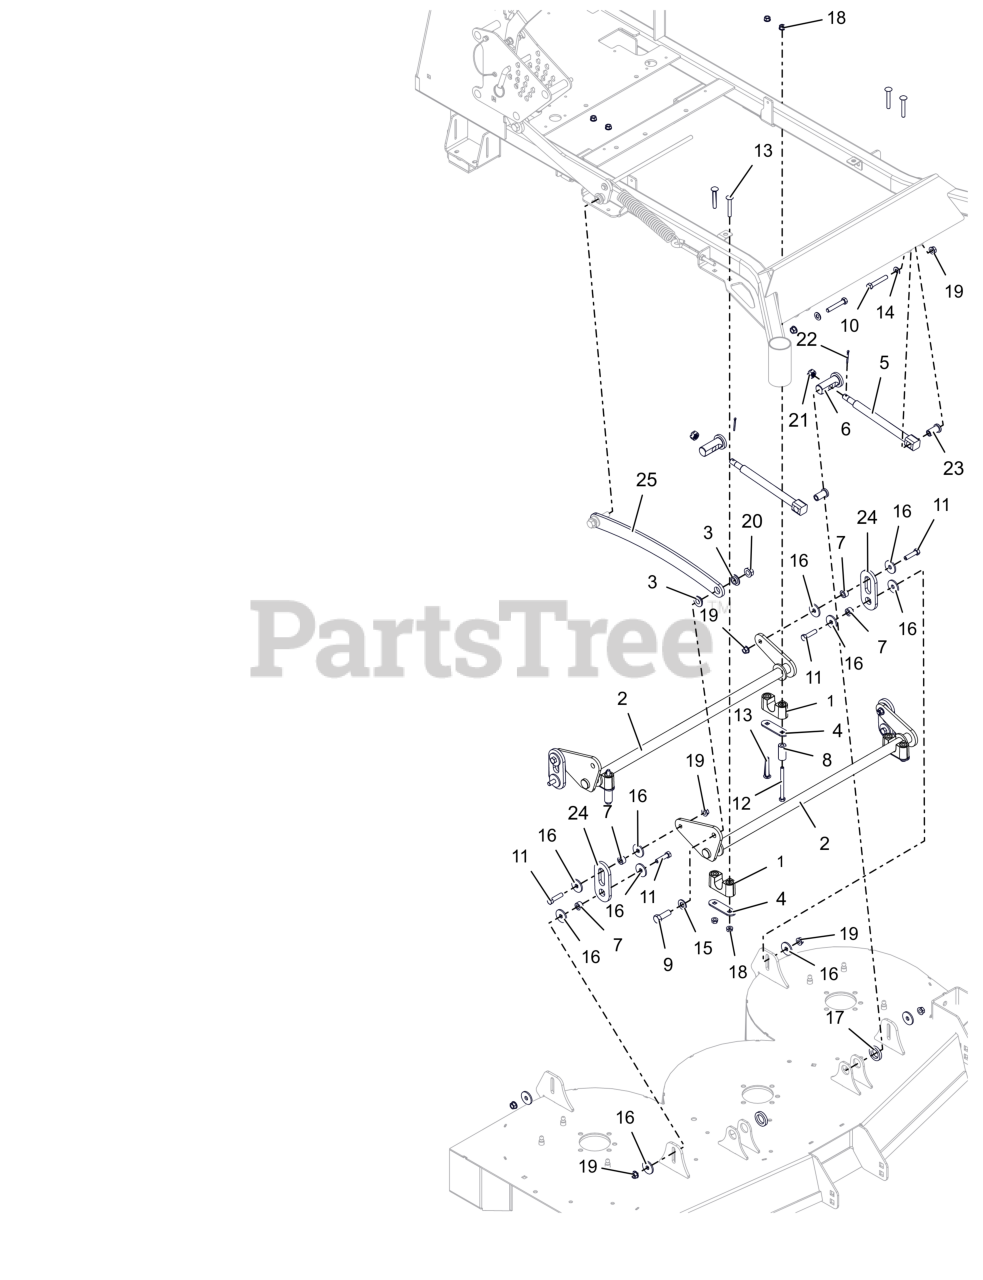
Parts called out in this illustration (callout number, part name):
1	ASM-BUSHING, DECK LIFT
2	WLDMT, 48-52" DECK LIFT SHAFT (BLACK)
3	BSHG-FLG .515X.750X.395X1.120
4	PLATE, BEARING SUPPORT
5	DRAG,LINK-HD
6	PIN, DECK LIFT
7	SPCR, .390 ID X .750 OD X .438
8	SPCR, .328 ID X .750 OD X 1.622
9	BLT,HEX .50-13X1.50 G5 ZCC
10	BLT,HEX .38-16X2.25 G5 ZCC
11	BLT, HEX .38-16X1.50 G5 ZCC
12	BLT, HEX .31-18X3.75 G5 ZCC
13	BLT, RHSSN.31-18X2.25 G5 ZCC
14	WSHR,FLT .406X.812X.065 ZCC
15	WSHR,FLT .531X1.062X.095 ZCC
16	WSHR,FLT .406X1.375X.135 ZCC
17	WSHR-FL-STL 1.0X1.50X.25
18	NUT,LK-CTR-FLG .31-18 GF ZCC
19	NUT-LK-CTR-FLG .375-16 GF ZCC
20	NUT-LK-CTR-FLG .500-13 GG ZCC
21	NUT-SL .50-13
22	PIN,CTR.12X1.25EXTPRSQCT ZC120
23	SPCR, DRAG LINK
24	PLATE, DECK HANGER (BLACK)
25	LINK, DECK 48-52" DECK LIFT CONNECTING(BLACK)
